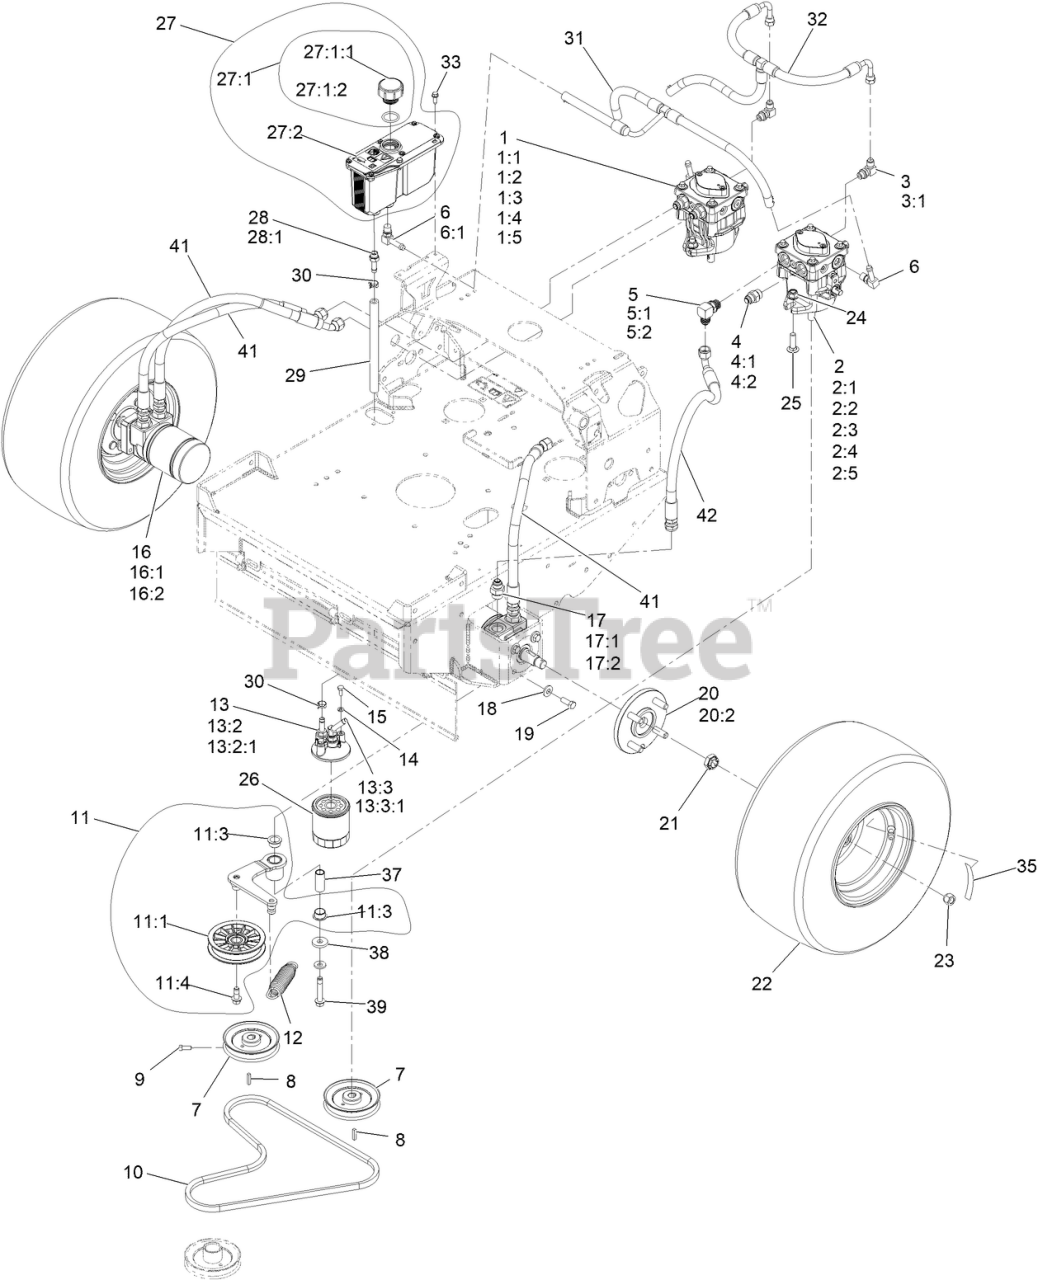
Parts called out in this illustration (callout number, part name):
1	PUMP-HYD PE RH TTH
1:1	INPUT SHAFT KIT
1:2	BEARING-THRUST
1:3	CYLINDER BLOCK KIT
1:4	SEAL OVERHAUL KIT
1:5	KIT, 10CC/12CC PUMP KIT
2	PUMP-HYD PE LH TTH
2:1	INPUT SHAFT KIT
2:2	BEARING-THRUST
2:3	CYLINDER BLOCK KIT
2:4	SEAL OVERHAUL KIT
2:5	KIT, 10CC/12CC PUMP KIT
3	FITTING-ELBOW, 90 DEG
3:1	O-RING
4	FITTING-STRAIGHT
5	FITTING-90 DEG
6	FITTING-ELBOW, 90
6:1	O-RING
7	SHEAVE ASM
9	SCREW-SET, SQH
10	BELT
11	ASM, PUMP IDLER
11:1	PULLEY-IDLER, FLAT
11:3	BUSHING-FLANGE
11:4	SCREW-HFH
12	SPRING-EXTENSION
13	ASM, FILTER HEAD
13:2	ADAPTER-STRAIGHT
13:2:1	O-RING
13:3	FITTING-BARBED, 45 DEG
13:3:1	O-RING
14	WASHER-LOCK
15	SCREW-HH
16	HYD MOTOR ASM
16:1	SEAL KIT
16:2	BEARING AND SEAL KIT
17	FITTING-STRAIGHT
17:1	O-RING
18	WASHER-BELLEVILLE
19	SCREW-HH
20	WHEEL HUB ASM
20:2	STUD-WHEEL
21	NUT-LOCK
22	ASM, WHEEL AND TIRE 18X8.50X8
23	NUT-LUG
24	NUT-HF, NI
25	BOLT-CARR
26	FILTER-25 MICRON, BI-DIRECTIONAL
27:1	Reservoir-HYD
27:1:1	Cap-Reservoir, HYD
27:2	DECAL-WARNING
28	ADAPTER-STRAIGHT
28:1	O-RING
29	HOSE-CHARGE
30	CLAMP-HOSE
31	HOSE, CASE
32	HOSE, CHARGE
33	SCREW-HWH, THREAD ROLL
35	DECAL-TORQUE WHEEL LUG-HU
37	PIVOT, IDLER
39	SCREW-HHF
41	HOSE,HYDRAULIC W/COVER
42	HYD HOSE ASM
